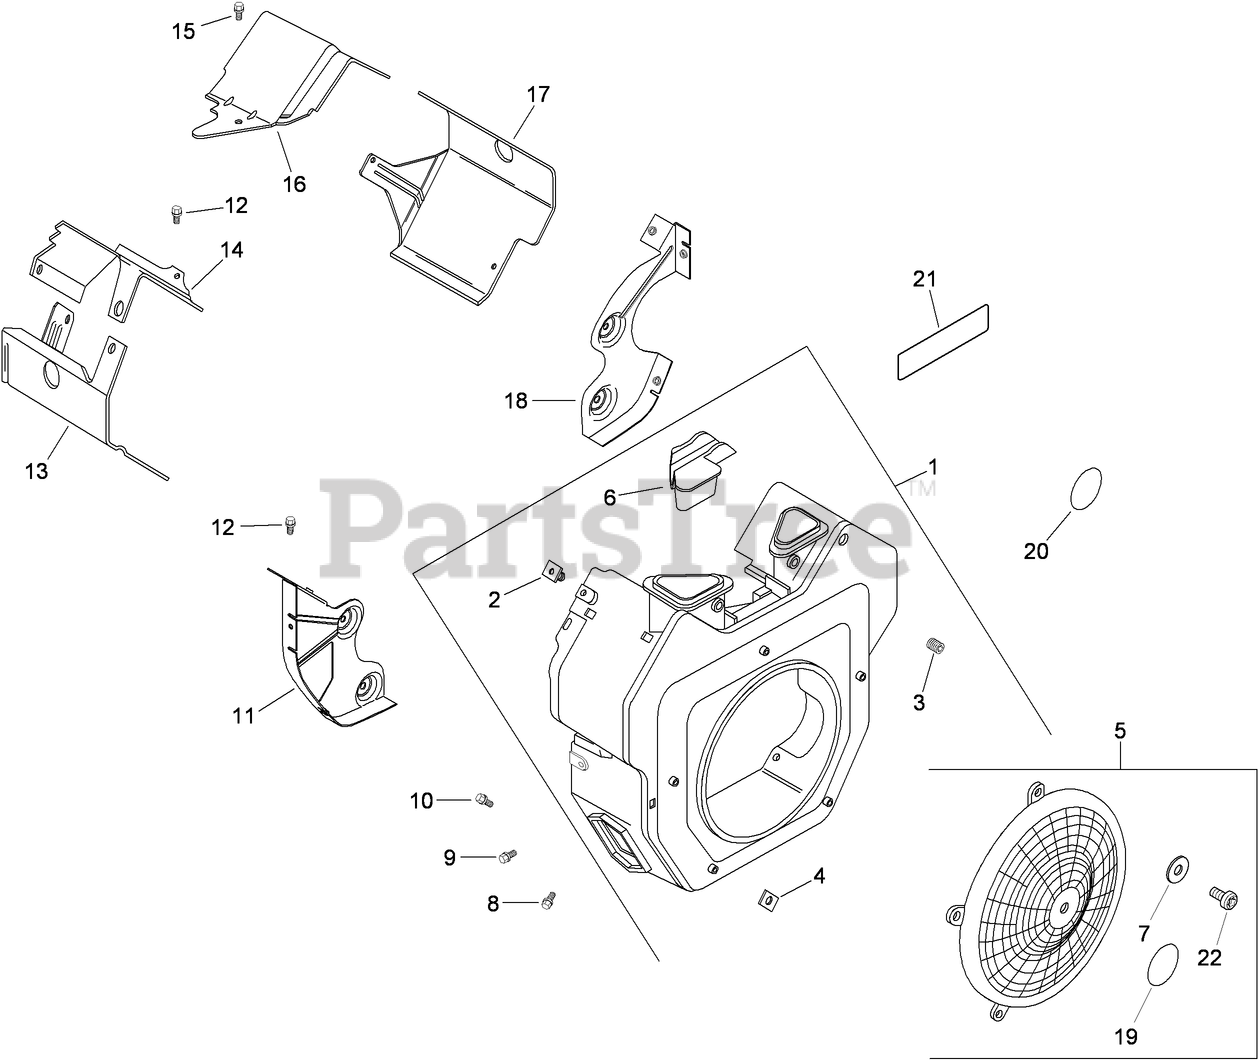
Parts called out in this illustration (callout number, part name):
1	Blower Housing ASM (Includes Ref 2-4, 6)
2	NUT-PLASTIC
3	Screw-Set (10-24X.25)
4	Nut-Plastic
5	FIXED GUARD KIT (Includes Ref 7, 19, 22)
6	Cover-Housing, Blower
7	INSERT-THREADED
8	Screw-Hex Flange, Heavy (M5x0.8x16)
9	SCREW-FLANGE, THREAD FORMING (M5X0.8X16)
10	SCREW-FLANGE, THREAD FORMING (M5X.8X20)
11	Plate-Backing (No. 2 Side)
12	SCREW-FLANGE, THREAD FORMING (M6X1.0X16)
13	Baffle-Barrel, Cylinder (No. 2 Side)
14	Baffle-Valley (No. 2 Side)
15	SCREW-HHFTF (M5X.80X10)
16	BAFFLE-VALLEY (No. 1 SIDE)
17	Baffle-Barrel, Cylinder (No. 1 Side)
18	Plate-Backing (No. 1 Side)
19	DECAL-SCREEN, GRASS
20	Decal-Screen, Grass
21	Decal-22HP
22	SCREW-SEMS
